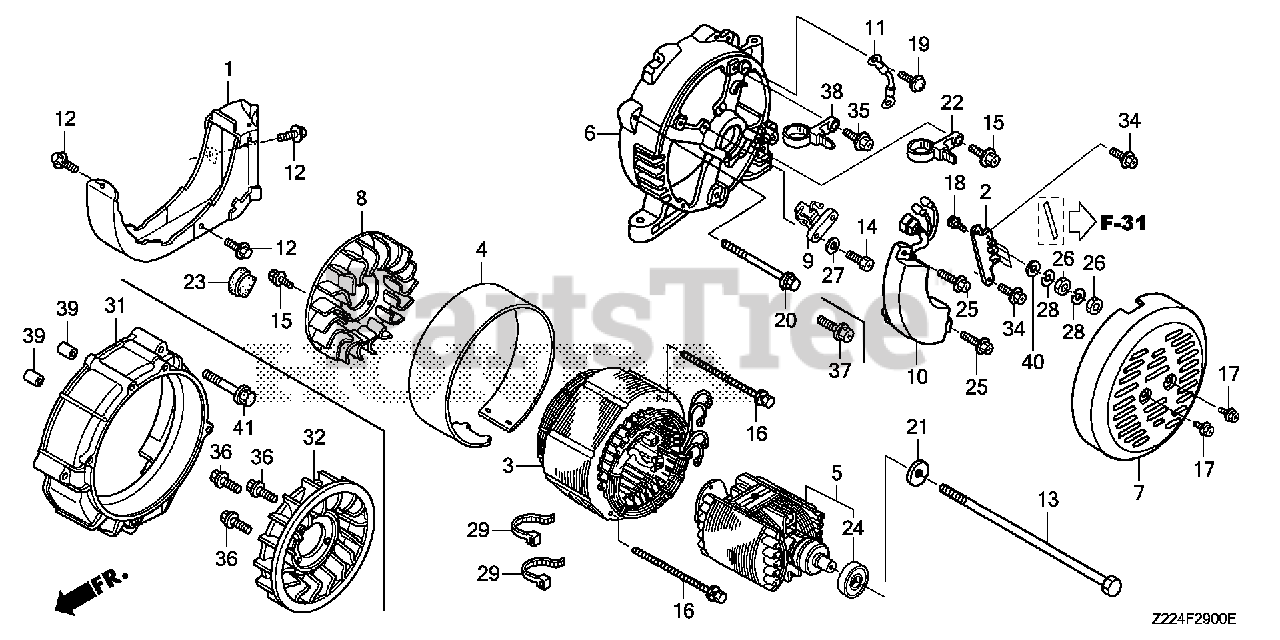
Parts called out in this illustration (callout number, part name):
1	COVER, DUCT
2	TERMINAL, VOLT CHANGE
3	STATOR ASSY.
4	COVER, STATOR *NH105* (MAT BLACK)
6	HOUSING, RR.
7	COVER, GENERATOR END *NH105* (MAT BLACK)
8	FAN, GENERATOR COOLING
9	BRUSH ASSY.
10	REGULATOR ASSY., AUTOMATIC VOLTAGE
11	WIRE, GROUND
12	BOLT, FLANGE (5X10)
13	BOLT, HEX. (10X265)
14	SCREW, TAPPING (5X18)
15	SCREW, TAPPING (5X14)
16	BOLT-WASHER (5X210)
17	SCREW, TAPPING (5X12)
18	BOLT, HEX. (5X20)
19	SCREW, PAN (5X12) (GROUND CABLE)
20	BOLT, FLANGE (6X175)
21	WASHER (10.5MM)
22	TIE, CABLE
23	GROMMET, CRANKCASE
24	BEARING ASSY. (6204)
25	SCREW, TAPPING (5X20)
26	NUT, HEX. (5MM)
27	WASHER, PLAIN (5MM)
28	WASHER, SPRING (5MM)
34	SCREW, TAPPING (5X14)
35	SCREW, TAPPING (5X14)
38	TIE, CABLE
40	WASHER, PLAIN (5MM)
